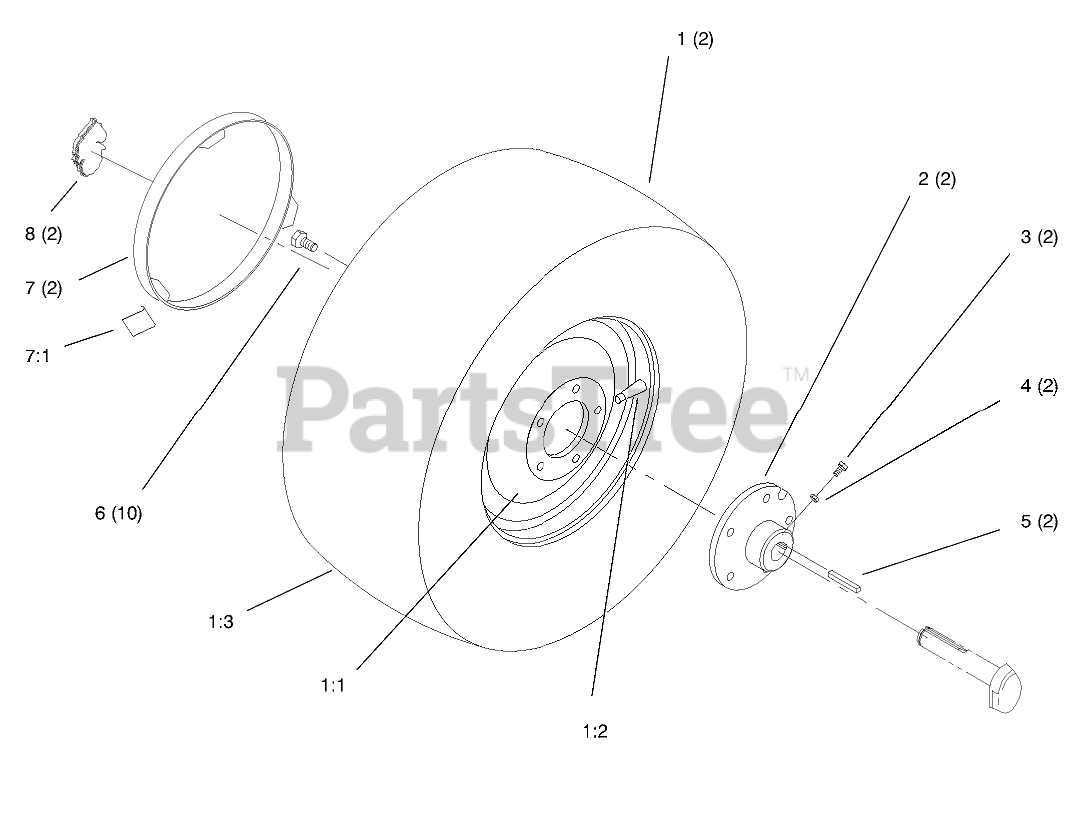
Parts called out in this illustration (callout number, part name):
1	Wheel & Tire ASM Rear
1:1	WHEEL
1:2	VALVE
1:3	TIRE 23 X 10.50-12
2	HUB-WHEEL
3	SCREW-SET, SQH
4	NUT-JAM
5	KEY-SQUARE
6	BOLT-LUG
